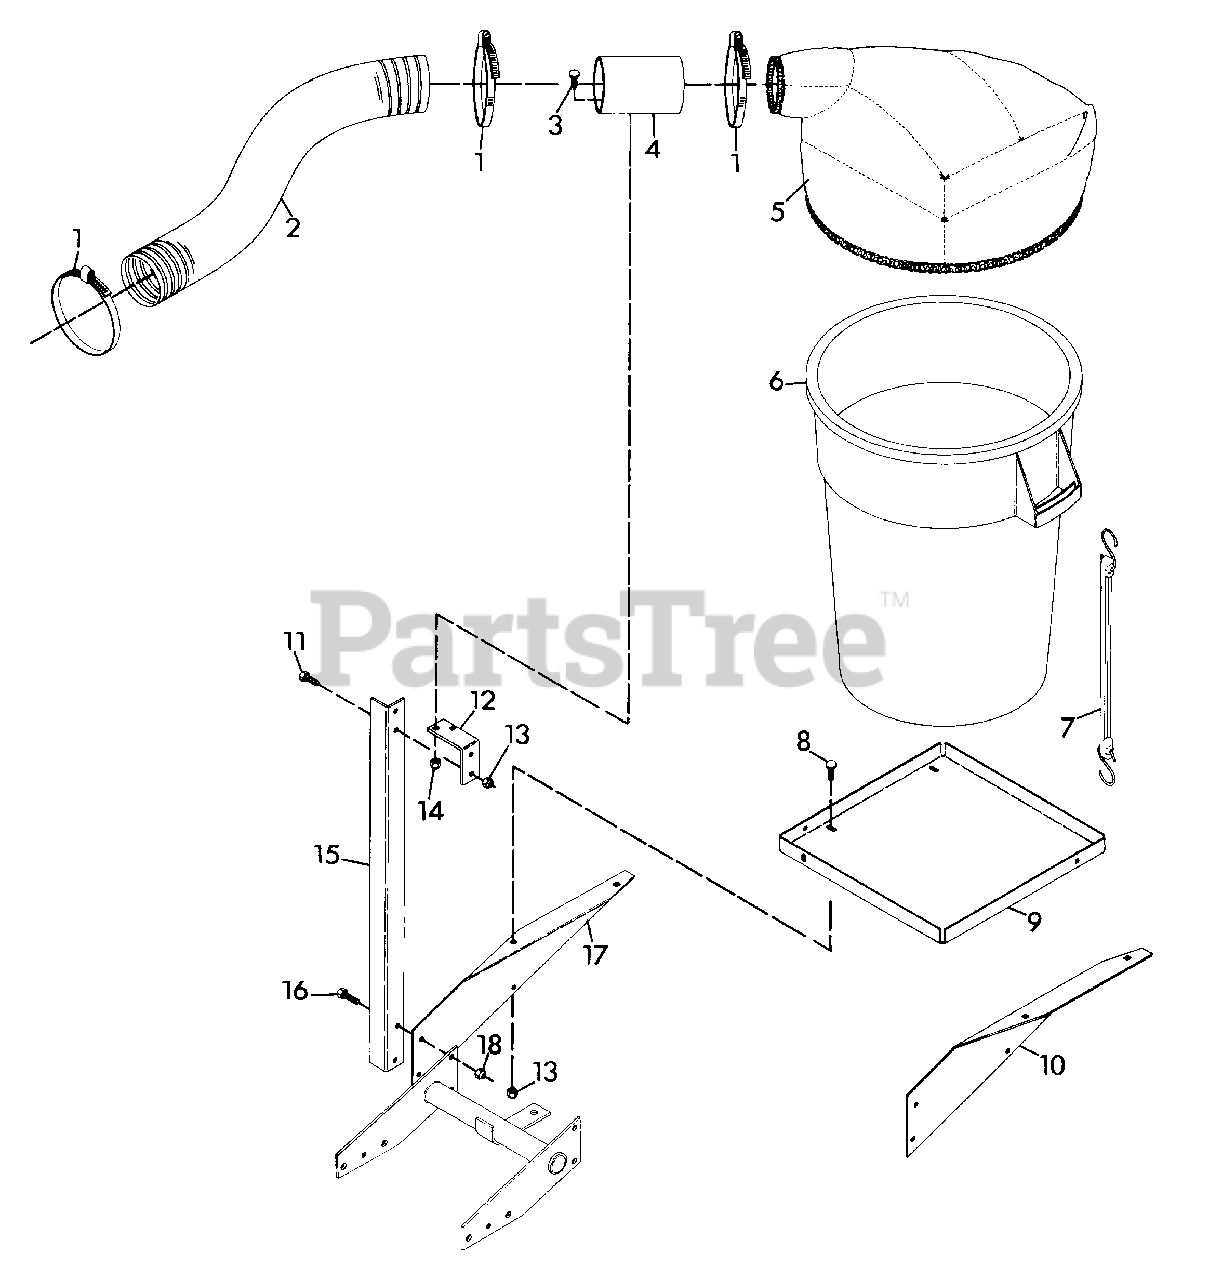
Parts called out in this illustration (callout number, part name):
1	CLAMP
2	HOSE, BLOWER TO CAN
3	BOLT, 5/16-18X.625 RD HD SQ NK
4	TUBE, CONNECTOR
5	COVER, TOP
6	CAN, GRASS
7	STRAP, HOLD DOWN
8	BOLT, 3/8-16X1 RD HD SQ NK
9	TRAY, SUPPORT
10	RAIL, LEFT SIDE
11	BOLT, HEX 3/8-16X1
12	BRACKET, TUBE
13	NUT, LOCK 3/8-16
14	NUT, LOCK 5/16-18
15	SUPPORT, TUBE
16	BOLT, HEX 1/2-13X1.25
17	RAIL, RIGHT SIDE
18	NUT, LOCK 1/2-13
